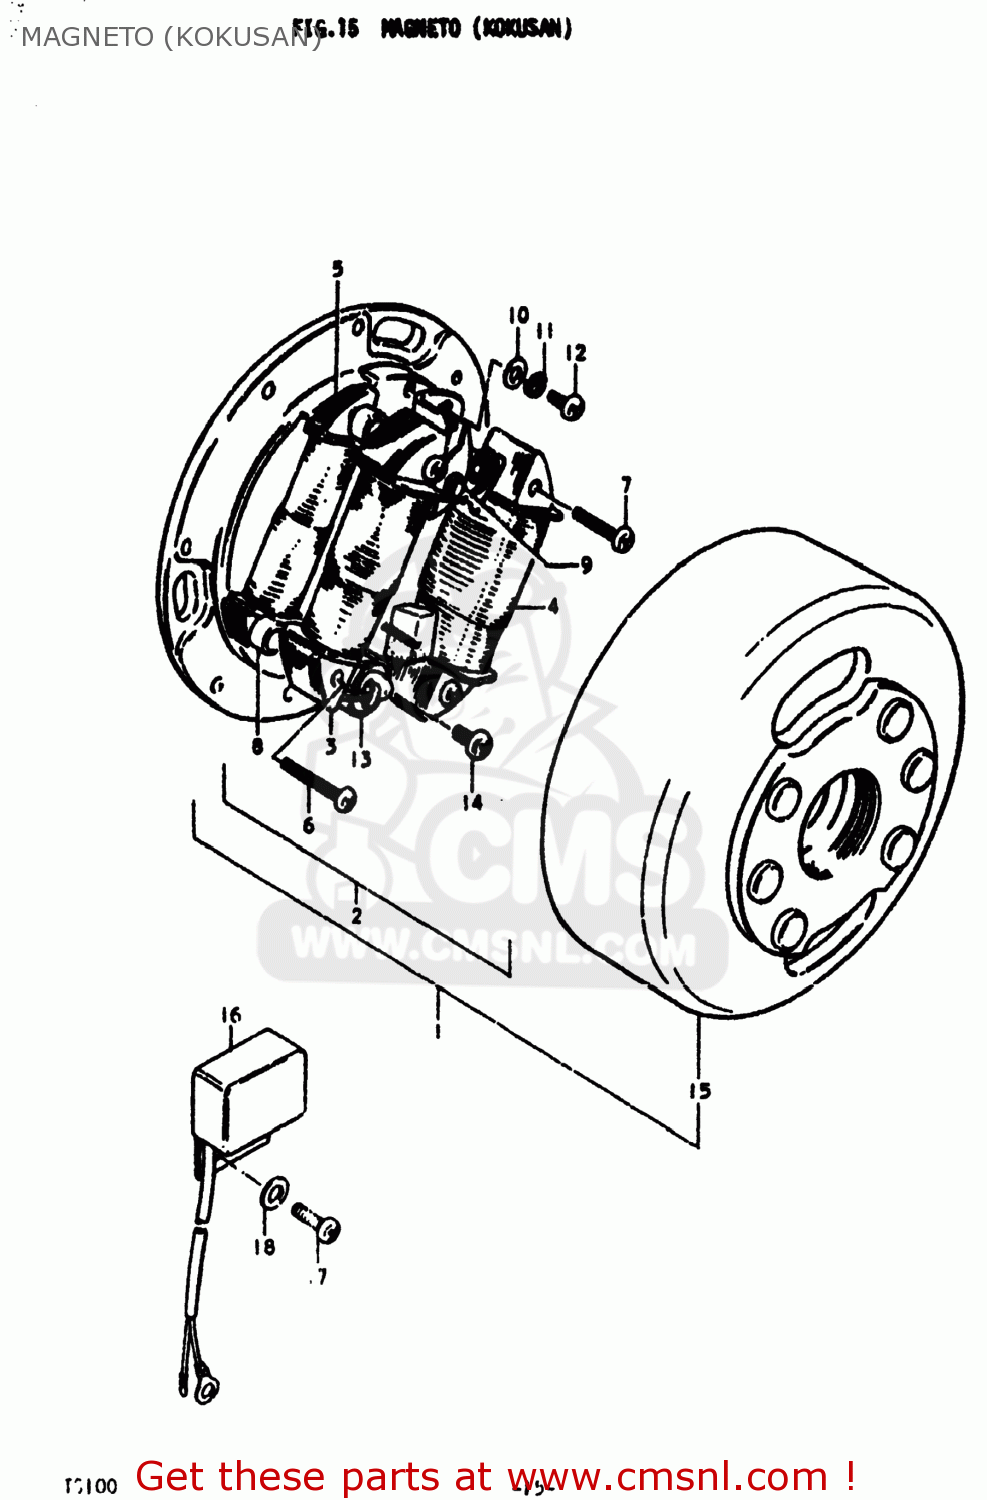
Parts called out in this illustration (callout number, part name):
1	MAGNETO ASSEMBLY
2	STATOR ASSEMBLY
3	COIL,PRIMARY
4	COIL,LIGHTING
5	COIL
6	SCREW
7	SCREW 4X25
9	POINT ASSY,CONTACT
10	WASHER
11	LOCK WASHER
12	SCREW(4X10)
13	CONDENSER
14	SCREW
15	ROTOR ASSEMBLY
16	REGULATOR ASSEMBLY
17	SCREW 6X12
